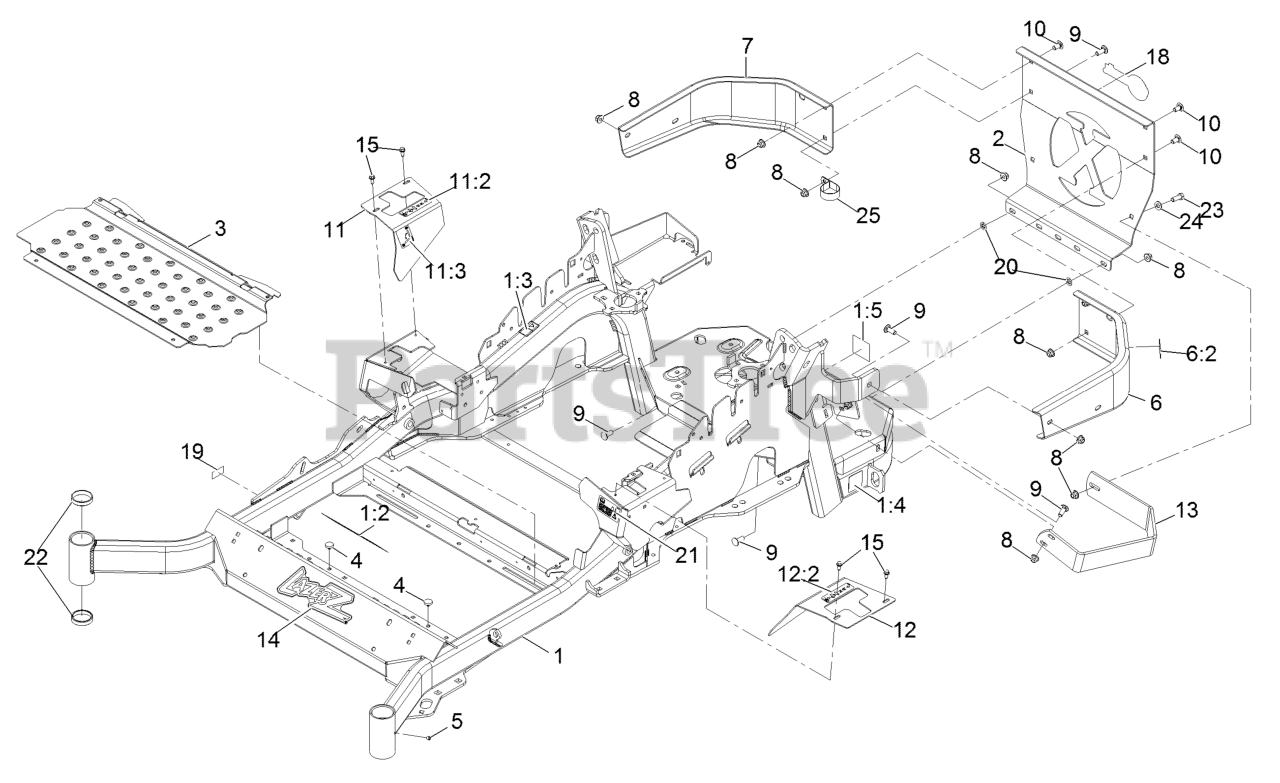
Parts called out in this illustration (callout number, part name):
1	MAINFRAME ASM
1:2	DECAL-WARNING, SLOPE
1:3	DECAL-WARNING
1:4	DECAL-HAZARD, PINCHED FINGER
1:5	DECAL-SPARK ARRESTER
2	PLATE,REAR GUARD
6	LH BUMPER ASM
6:2	DECAL-WARNING
7	BUMPER-RH
8	NUT-HF, NI
9	SCREW-CARR
10	SCREW-CARR
11	RH MOTION CONTROL COVER ASM
11:2	DECAL-CONTROL, MOTION
11:3	DECAL-PARK BRAKE, CE
12	LH MOTION CONTROL COVER ASM
12:2	DECAL-CONTROL, MOTION
13	GUARD-MUFFLER
14	DECAL,LAZER MODEL
15	SCREW-HWH
19	Decal-Patent Ttco.Com
20	NUT-PUSH
21	DECAL-FUEL FILL, CE
22	CUP-BEARING
23	SCREW-HH
24	WASHER-FLAT
25	CLAMP-R
